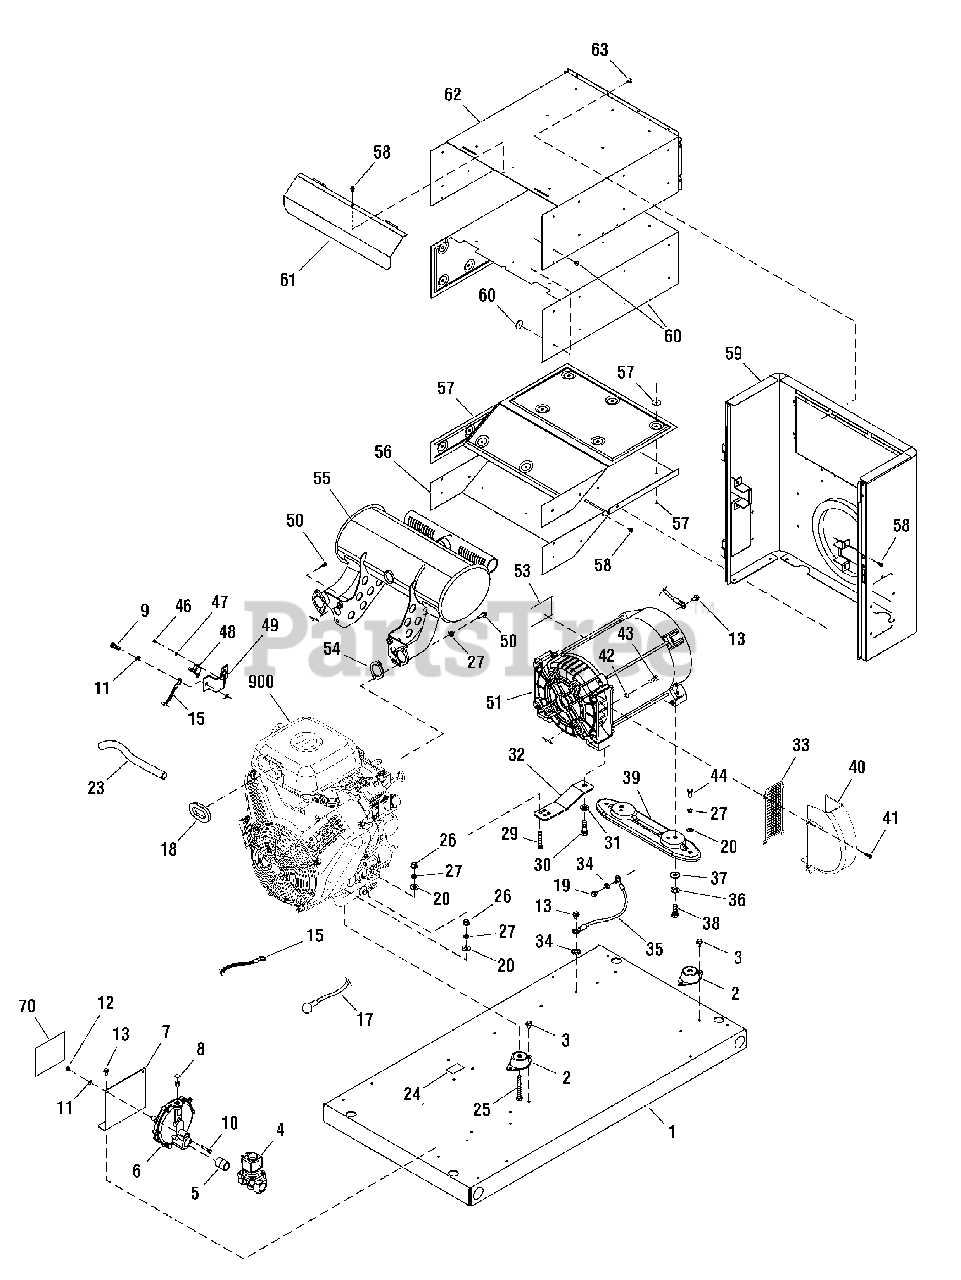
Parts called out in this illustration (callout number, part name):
2	MOUNT, Vibration
4	SOLENOID, Gas Fuel
6	REGULATOR, NG/LPG
9	* CAPSCREW, Hex Head, M6-1.0 x 16
10	* CAPSCREW, Hex Head, M6-1.0 x 30
11	* WASHER, Lock, 1/4
12	* NUT, M6-1.0
13	BOLT
15	CABLE, Battery, Black
17	CABLE, Battery, Red
18	SEAL, Foam
20	* WASHER, Flat, 5/16-M8
24	DECAL, Oil Drain
25	* CAPSCREW, Hex Head, 5/16-18 x 2-1/2
26	* NUT, 5/16-18
27	* WASHER, Lock, 5/16-M8
29	* CAPSCREW, Hex Head, 5/16-18 x 2
30	* CAPSCREW, Hex Head, M12-1.75 x 35
31	* WASHER, M12
32	SUPPORT, Engine
34	* WASHER, Shakeproof, M6
36	* WASHER, Lock, 3/8
37	* WASHER, Flat, 3/8 - M10
38	* CAPSCREW, Hex Head, 3/8-16 x 1
41	* SCREW, Taptite, M5.8 x 10
42	* WASHER, Lock, 3/8
43	* CAPSCREW, Socket Head, 3/8 x 1-1/4
44	* CAPSCREW, Hex Head, 5/16-18 x 3/4
46	* SCREW, Phillips Head, 4-40 x 0.19
47	* WASHER, Lock, #4
49	PLATE, Temp Switch
50	SCREW
51	ALTERNATOR
53	DECAL
59	BULKHEAD, Alternator
62	BOX, Muffler Top
900	** ENGINE
